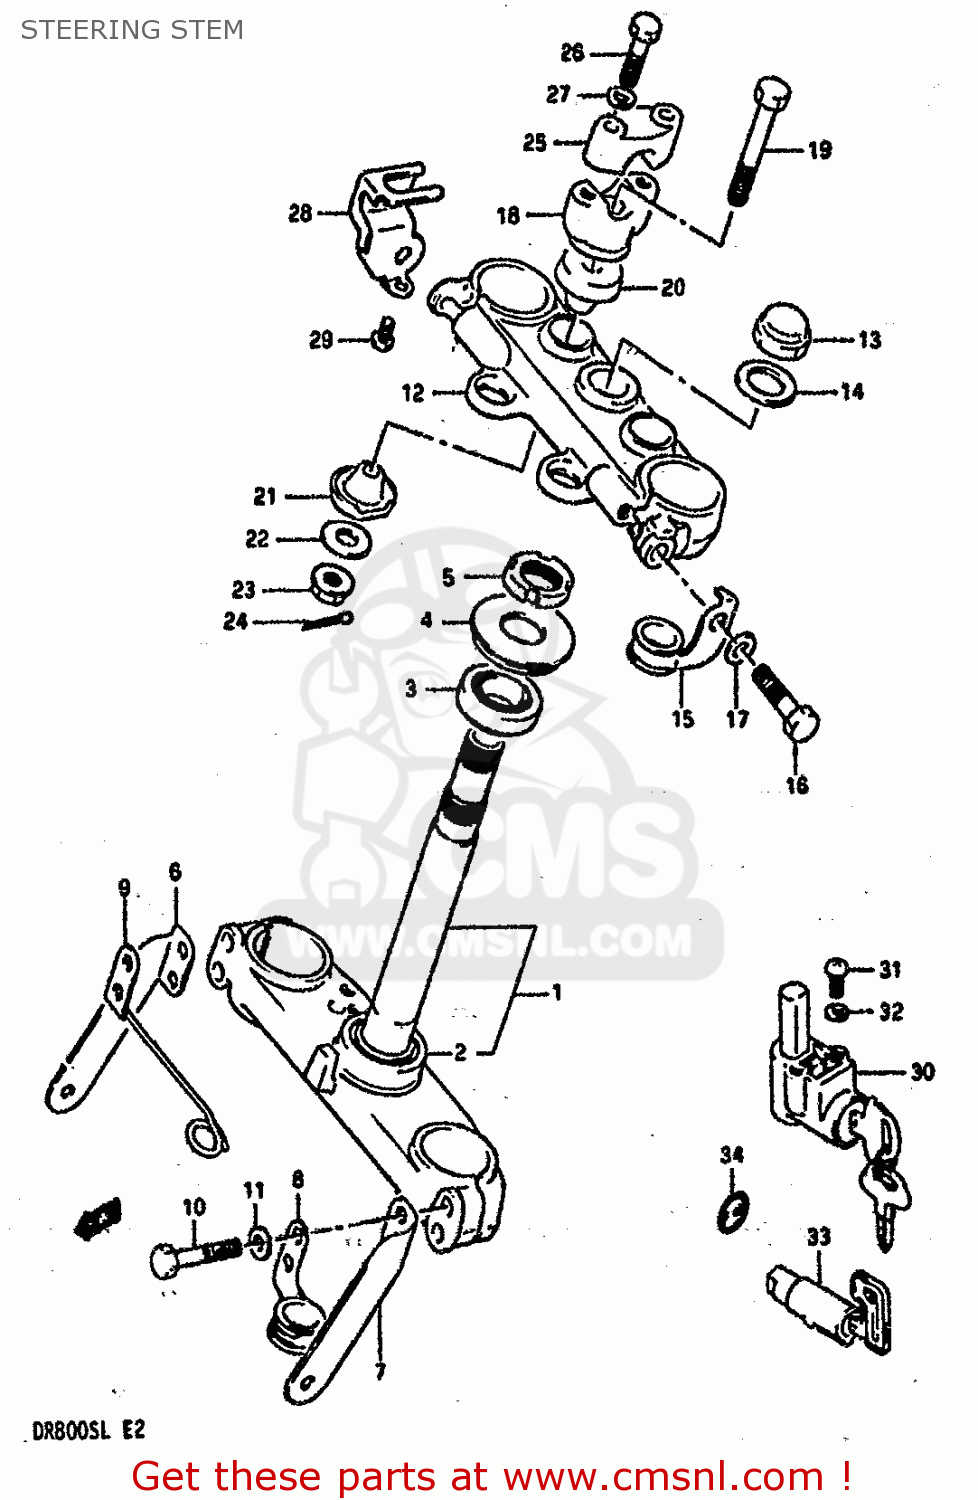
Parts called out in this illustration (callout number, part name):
1	STEM,STEERING
2	BEARING(30X55X17)
3	TAPER,ROLLER BEARING
4	SEAL,STEERING UPR DUST
5	NUT,STEERING STEM
6	BRACKET,FRONT SIDE RH
7	BRACKET,FRONT SIDE LH
8	CLIP,LH LOWER
9	GUIDE, SPEEDOMETER CABLE
10	BOLT
11	LOCK WASHER
12	BRACKET,UPPER
13	NUT
14	WASHER,STEERING STEM
15	CLIP,UPPER LH
16	BOLT
17	LOCK WASHER
18	HOLDER,HANDLE LWR
19	BOLT,HANDLE HOLDER
20	DAMPER,UPR
21	DAMPER RUBBER,LOWER
22	WASHER
23	NUT
24	COTTER PIN
25	HOLDER,HANDLE UPR
26	BOLT
27	WASHER,LOCK,8.
28	BRACKET,STARTER CABLE
29	SCREW
30	LOCK ASSY,STEERING
31	SCREW
32	LOCK WASHER
33	LOCK ASSY,STEERING(NEIMAN)
34	LABEL,STEERING LOCK
